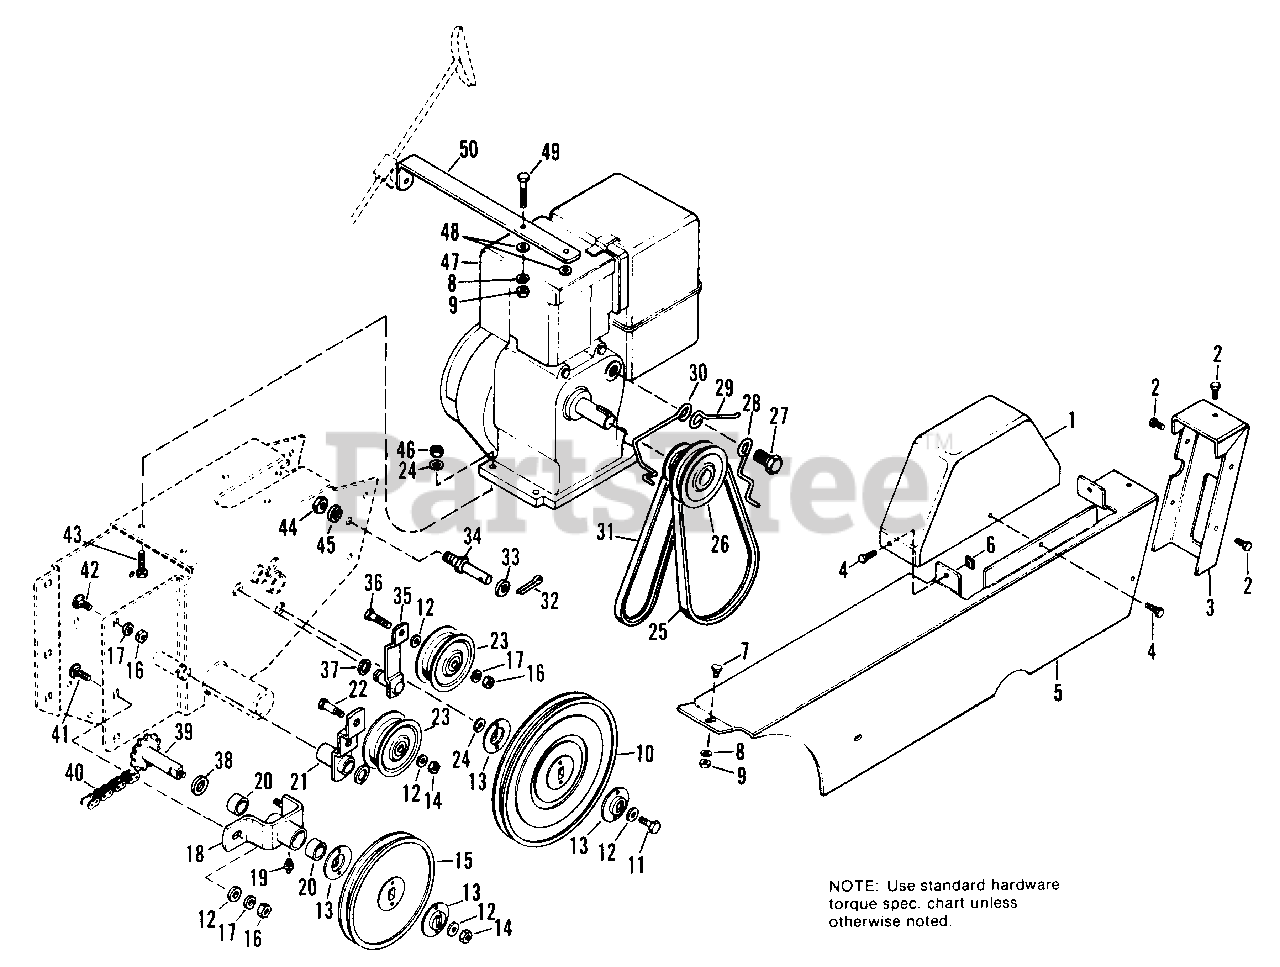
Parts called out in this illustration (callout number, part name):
1	COVER, Top, Belt
2	SCREW, Ind. Washer Hd., Taptite, 1/4-20 x 3/8
3	SUPPORT, Belt Cover
4	SCREW, Self Tapping, 1/4-20 x 5/8
5	COVER, Lower
6	NUT, Retainer
7	CAPSCREW, Hex Hd., 1/4-20 x 1/2
8	LOCKWASHER, 1/4
9	NUT, Hex, Full, 1/4-20
10	PULLEY, Transmission
11	CAPSCREW, Hex Hd., 5/16-18 x 7/8
12	WASHER, Plain, 5/16
13	WASHER, Special
14	LOCKNUT, Jam, 3/8-16
16	NUT, Hex, Full, 3/8-16
17	LOCKWASHER, 3/8
18	HOUSING ASSY., Bearing
19	FITTING, Grease
21	LEVER ASSY., Idler
22	SCREW, Special
23	PULLEY, Idler
24	LOCKWASHER, 5/16
25	V-BELT (Transmission Drive)
26	PULLEY, Engine
27	CAPSCREW, Hex Hd., 1/2-20 x 1
28	STOP, Belt
29	STOP, Belt
30	STOP, Belt
31	V-BELT (Auger Drive)
32	PIN, Cotter, 1/8 x 3/4
33	WASHER, Plain, 3/8
35	ARM ASSY., Idler
36	CAPSCREW, Hex Hd., 3/8-16 x 1-1/4
37	RING, Retaining
39	SHAFT ASSY., Sprocket
40	CHAIN (Drive)
41	BOLT, Carriage, 3/8-16 x 1
42	BOLT, Carriage, 3/8-16 x 3/4
43	CAPSCREW, Hex Hd., 5/16-18 x 1-1/2
44	NUT, Hex, Full, 7/16-14
45	LOCKWASHER, 7/16
46	NUT, Hex, Full, 5/16-18
48	WASHER, Plain, 1/4
49	CAPSCREW, Hex Hd., 1/4-20 x 1-3/4
50	SUPPORT, Rod
